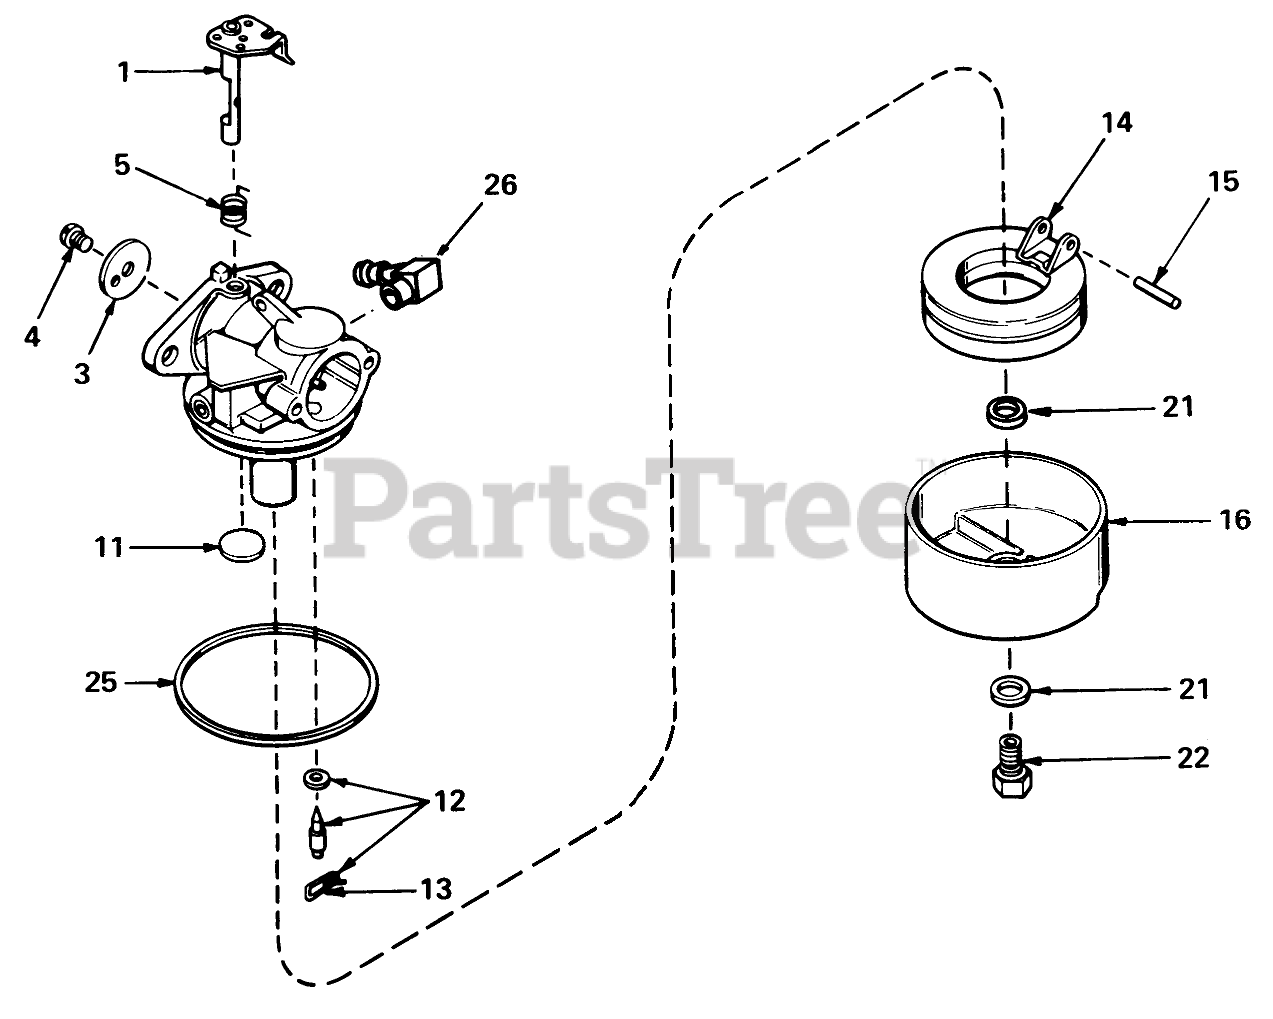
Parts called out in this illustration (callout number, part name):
1	Throttle Shaft and Lever ASM
3	Throttle-Shutter
4	Screw-Shutter
5	Spring, Return
11	Plug-Welch, Atmospheric Vent
12	Inlet Needle, Seat & Clip Assy. (Incl. No. 13)
13	Clip-Spring
14	Float,Carburetor
15	Shaft-Float
16	Bowl Float
21	Gasket-Bowl
22	Nut-Float Bowl
25	O Ring-Bowl, Float
26	Fitting-Fuel
